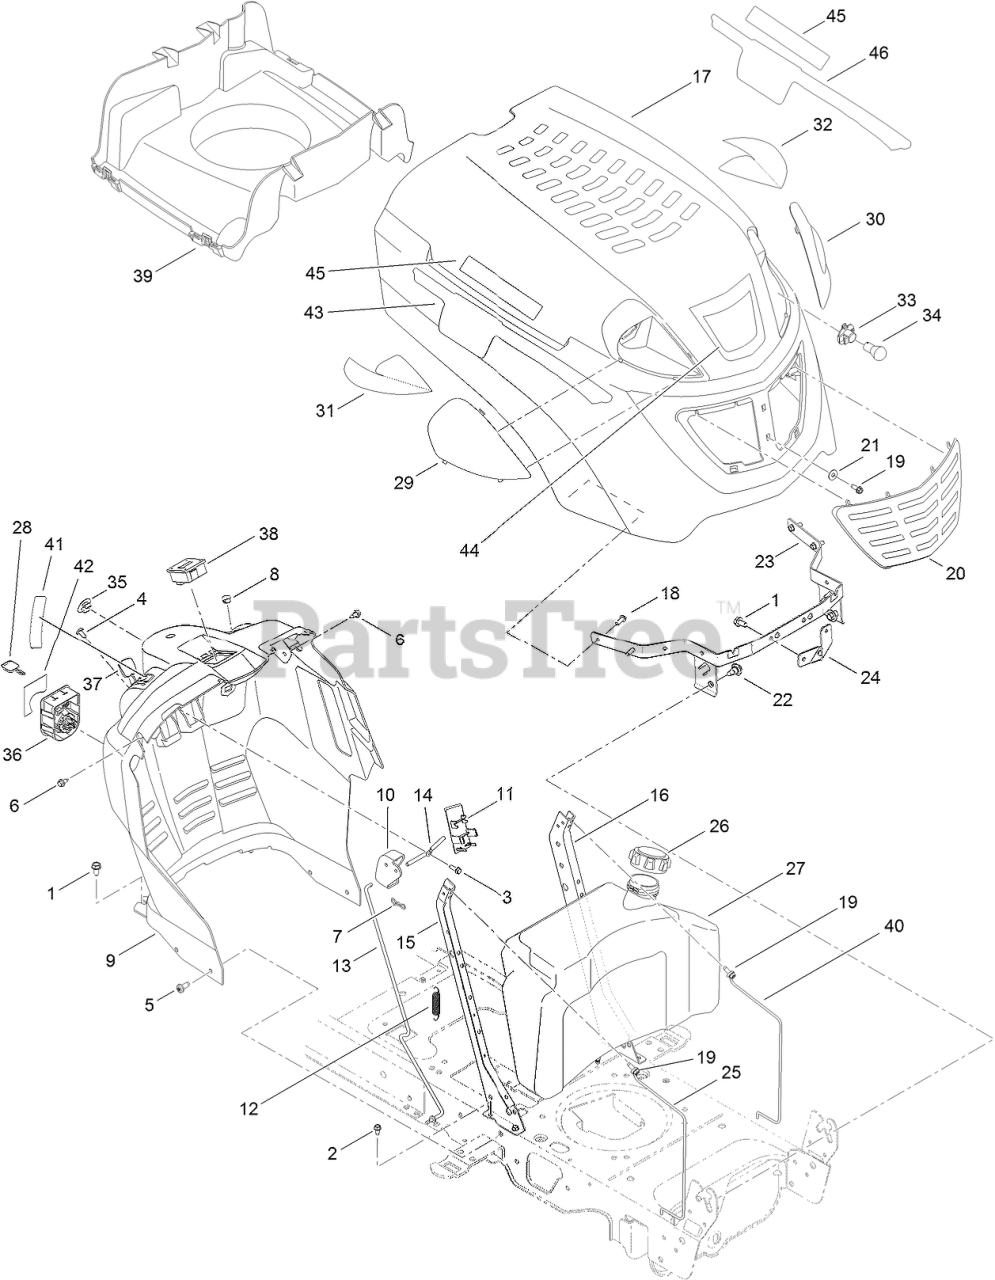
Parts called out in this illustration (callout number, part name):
1	SCREW-TAP
2	SCREW-HWHTF
3	SCREW-TAP
4	SCREW-TAP
5	SCREW-TAP
6	SCREW-HWH
7	PIN-COTTER
8	CAP-PLUG, HOLE
9	DASH-MANUAL, PTO
10	LEVER-DASH
11	COVER-CRUISE
12	SPRING-EXTENSION
13	ROD-LATCH
14	ROD-LEVER, BENT
15	SUPPORT-DASH, PLATE (RH)
16	SUPPORT-DASH, PLATE (LH)
19	SCREW-TAP
21	WASHER-FLAT
22	BOLT-SHOULDER, TAP
23	BRACKET-PIVOT
24	BRACKET-SUPPORT, HOOD
25	ROD-SUPPORT
26	CAP-FUEL
27	TANK-FUEL
28	KEY-IGNITION
29	LENS-RH
30	LENS-LH
31	REFLECTOR-RH
32	REFLECTOR-LH
33	SOCKET-HEADLIGHT
34	LAMP-12V, MINIATURE
35	PLUG-CHOKE
36	MODULE-SWITCH, IGNITION
37	CABLE-THROTTLE/CHOKE
38	METER-HOUR
39	PLENIUM-HOOD
40	ROD-SUPPORT, LH TANK
41	DECAL-THROTTLE
42	DECAL-SWITCH, IGNITION
43	DECAL-HOOD, RIGHT SIDE
44	DECAL-HOOD
46	DECAL-HOOD, LEFT SIDE
